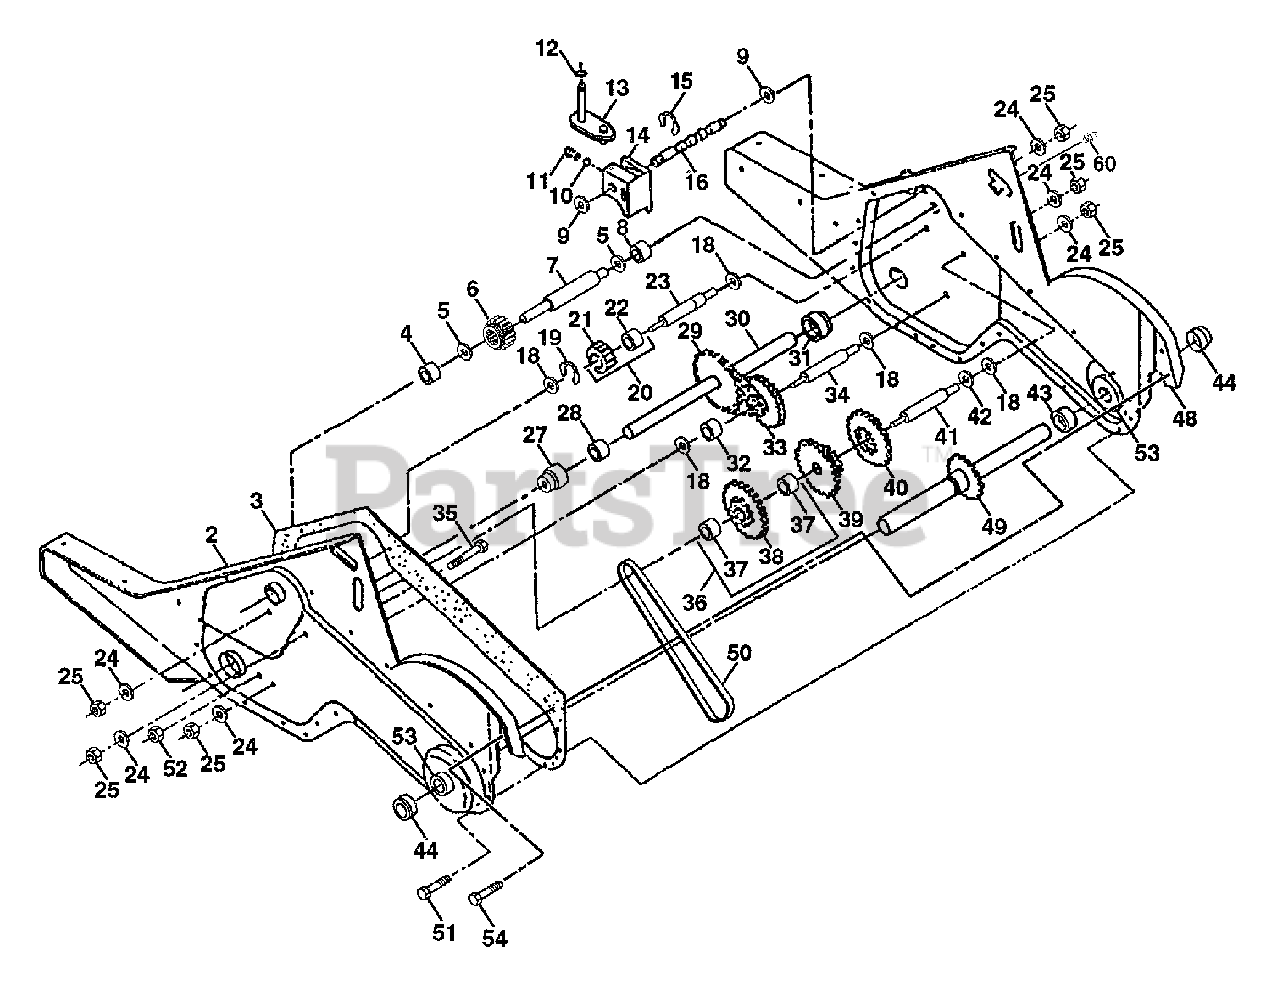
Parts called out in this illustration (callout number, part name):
1	Transmission Assembly
2	Gearcase, L.H. w/Bearing
3	Gasket, Gearcase
4	Bearing, Needle
5	Washer, Thrust 5/8 x 1.10 x 1/32
6	Pinion, Input
7	Shaft, Input
8	Bearing, Needle
9	Washer, Seal
10	Ball, Steel
11	Spring, Shift, Fork
12	O-Ring
13	Arm,. Shift
14	Fork, Shift
15	Ring, Klip
16	Shaft, Shift
18	Washer
19	Ring, Klip
20	Gear, Assembly, Reverse Idler
21	Gear, Reverse Idler
22	Bearing, Needle
23	Shaft, Reverse Idler
24	Washer, Lock 7/16
25	Nut, Hex 7/16-20
27	Bearing, Shaft, Ground Drive L.H.
28	Spacer 0.765 x 1.125 x 1.23
29	Chain #35-50 Pitch
30	Ground Shaft Assembly
31	Bearing, Shaft, Ground Drive R.H.
32	Spacer 0.70 x 1.00 x 1.150
33	Sprocket and Gear Assembly
34	Shaft, Reduction (2nd)
35	Screw, Whiz, Lock 5/16-18 x 3-1/2
36	Sprocket Assembly w/Bearing
37	Bearing, Needle
38	Sprocket, Tine
39	Gear, Cluster, Red 1st & 2nd
40	Gear, Reverse
41	Shaft, Reduction (1st)
42	Washer, Thrust
43	Spacer 1.01 x 1.75 x 0.760
44	Seal Asm. Oil
48	Gearcase, R.H. w/Bearing
49	Shaft, Tine
50	Chain, Roller #50-50 Pitch
51	Screw 1/4-20 x 1/2
52	Nut, Hex 5/16-18
53	Kit, Bearing, Tine Shaft
54	Screw 1/4-20 x 3/4
60	Fitting Grease
60	Grease, Plastilube #1
